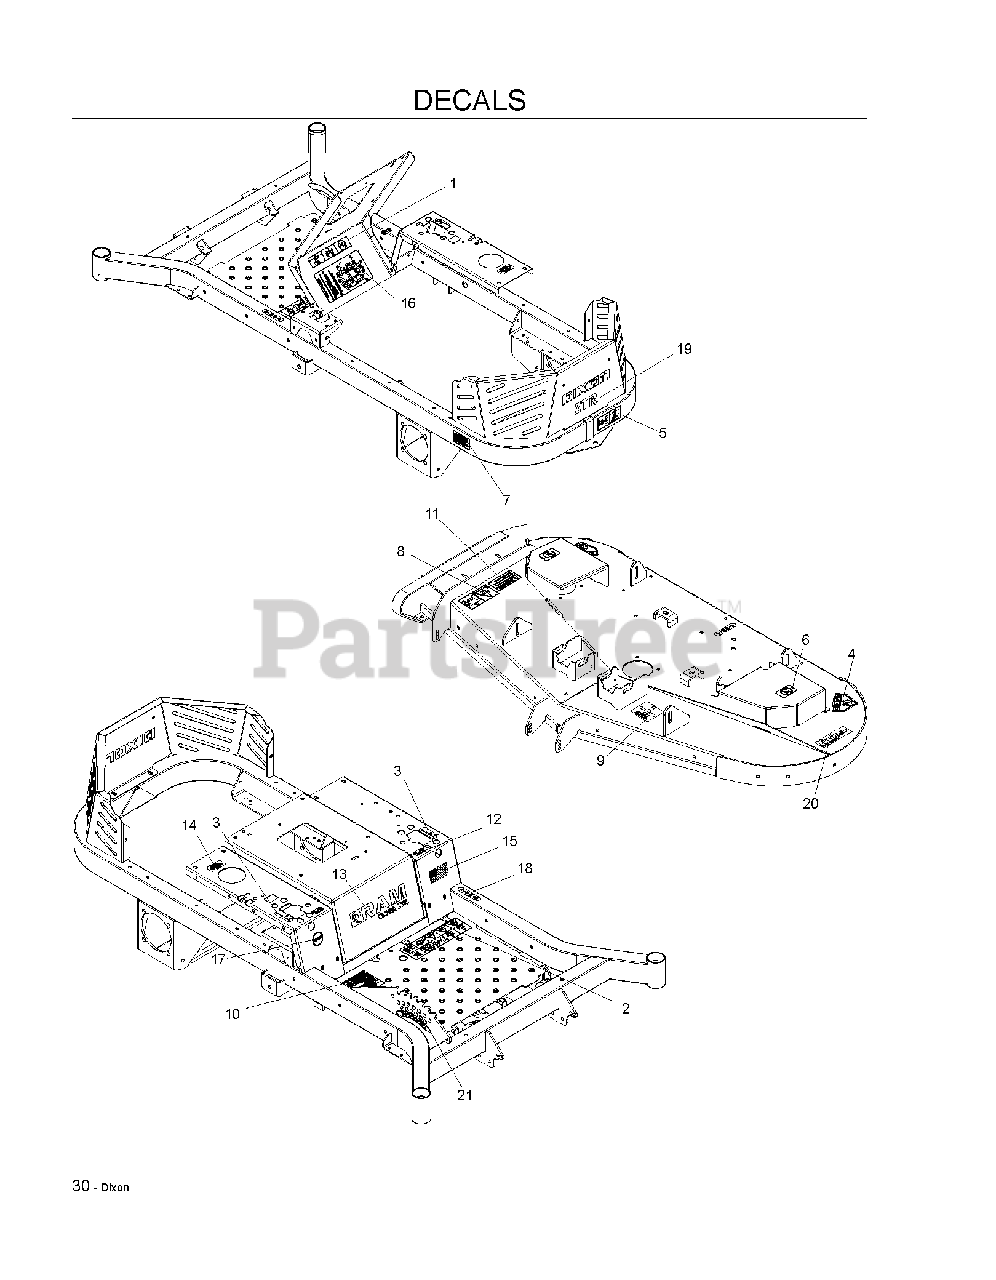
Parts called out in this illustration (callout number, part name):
1	DECAL, BATTERY
2	DECAL, WARNING
3	DECAL, MOTION CONTROL
4	DECAL, CPSC
5	DECAL, BELT DRIVE
6	DECAL, NO STEP
7	DECAL, PROP. 65
8	DECAL, EURO SEVERING
9	DECAL, BELT ROUTING (18656)
10	DECAL, WARNING
11	DECAL, CAUTION
12	DECAL, F.S.T.
13	DECAL, RAM ULTRA
14	DECAL, OIL TANK
15	DECAL, FLAG
16	DECAL, SERVICE
17	DECAL, KOHLER
18	DECAL, PARK BRAKE
19	DECAL, ZTR
20	DECAL, FUSION
21	DECAL, HEIGHT ADJUSTMENT
